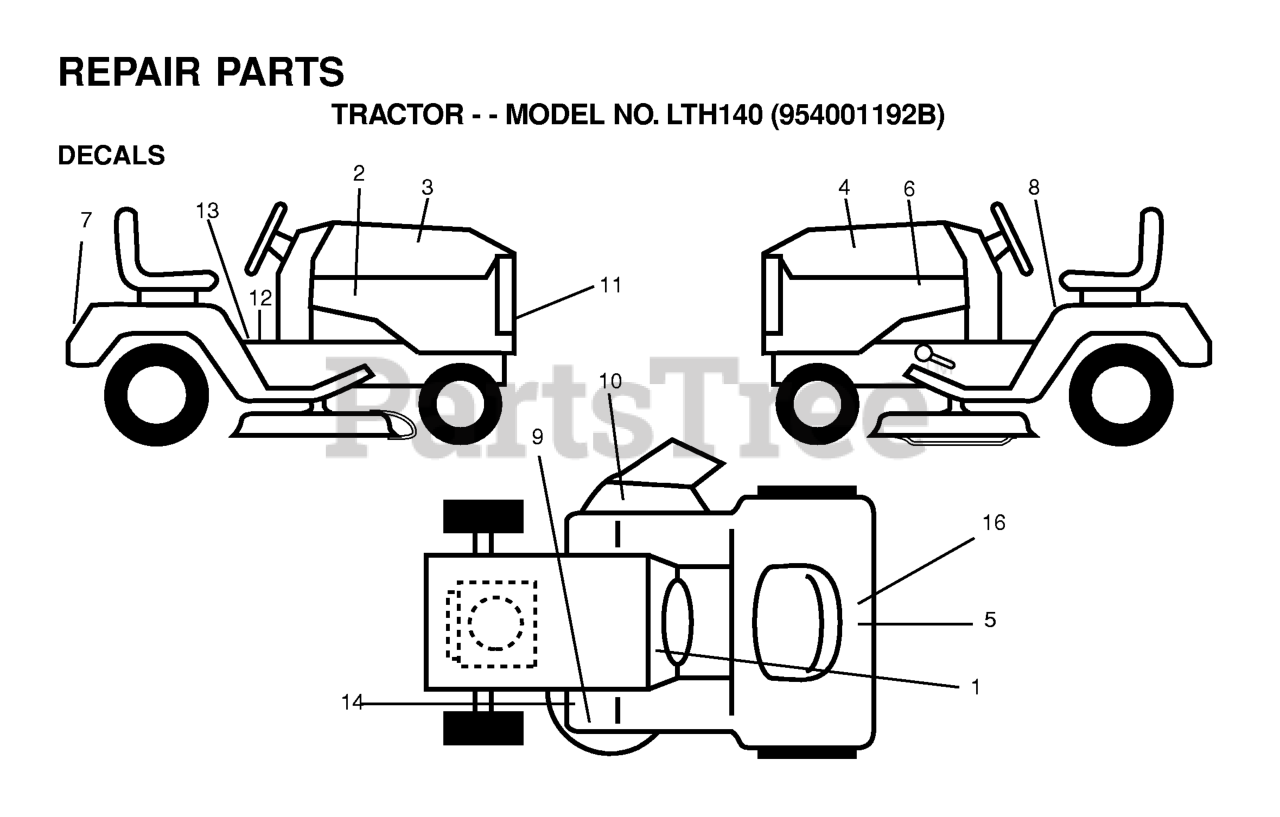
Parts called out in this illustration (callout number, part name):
3	DECAL-HOOD R.H.
4	DECAL-HOOD L.H.
7	DECAL FENDER NLA
8	DECAL CAUTION
10	DECAL WARNING (ENGLISH/FRENCH)
11	DECAL GRILL HUSQ NLA
13	DECAL PARK BRAKE
14	DECAL V-BELT SCHEMATIC
16	DECAL BTRY SYMBOLS
